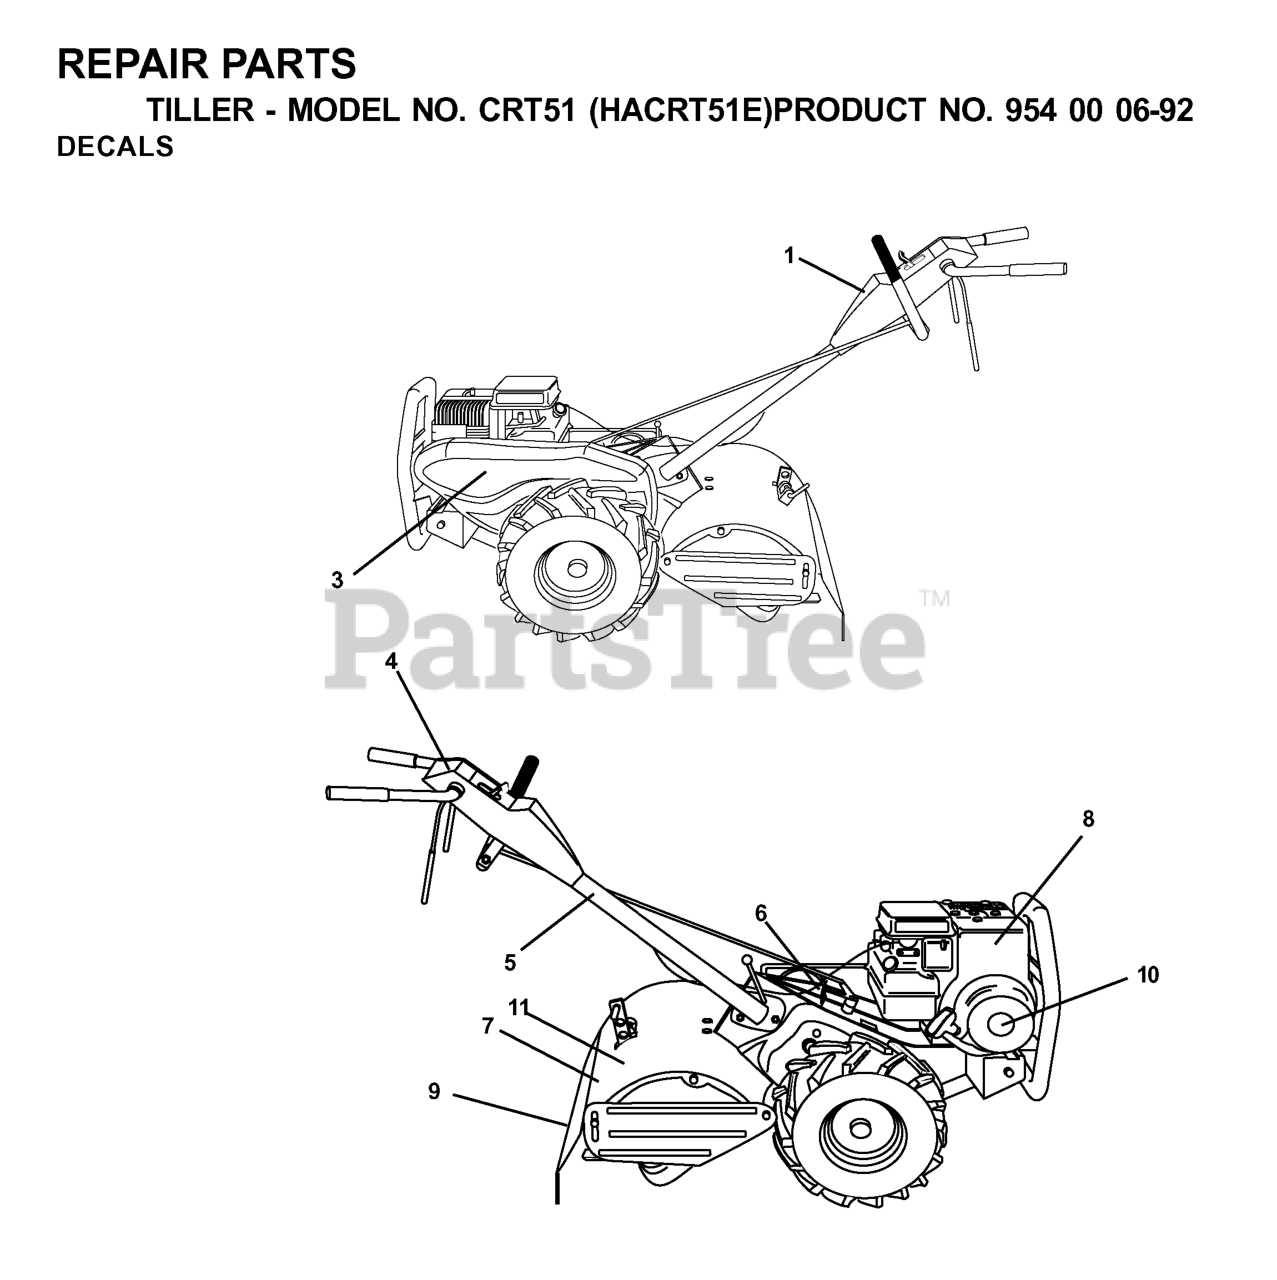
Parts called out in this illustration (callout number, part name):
1	DECAL, LOGO
4	DECAL, LOGO
5	DECAL, HAND PLACEMENT
6	DECAL.SHIFT.INDICATOR.TILLER
7	DECAL.TINE.SHIELD
11	DECAL
